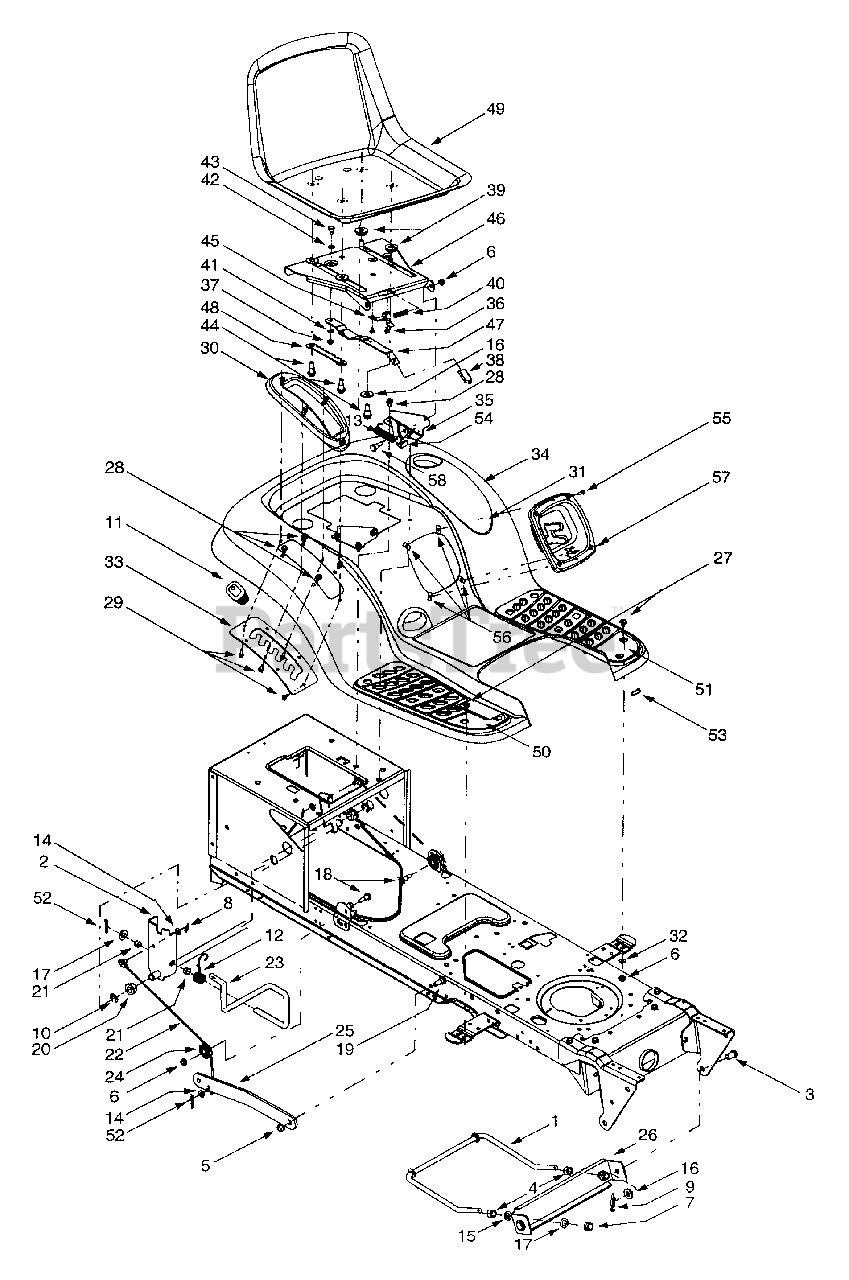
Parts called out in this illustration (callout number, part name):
1	Deck Stabilizer Rod
3	Clevis Pin, .5 x .78
4	Hex Nut, 1/2-13
5	Flange Lock Nut, 3/8-16
6	Flange Lock Nut, 5/16-18
7	Hex Nut, 1/2-13
8	Internal Cotter Pin
9	Internal Cotter Pin
10	E-ring
11	Handle Grip
12	Torsion Spring
13	Extension Spring, .872 x 3.4
14	Flat Washer, 5/16
15	Lock Washer, 1/2
16	Flat Washer, .31 x 1.062 x .134
17	Flat Washer, .51 x 1.12 x .06
18	Hex Cap Screw, 5/16-18 x .62
19	Shoulder Screw, 3/8-16
20	Hex Flange Bearing
21	Snap Flange Bearing
22	Lift Cable, 16.16
23	Lift Handle
24	Roller Pulley
27	Carriage Bolt, 5/16 x .62
28	Self-tapping Screw, 5/16-18 x .625
29	Self-tapping Screw, 1/4-15 x .75
30	Lift Lever Cover
31	Cover w/ Cup Holder
32	Flat Washer, .349 x 1.0 x .063
36	Screw, #10-16 x .375
37	Hex Flange Lock Nut, 1/4-20
38	Seat Adjuster Grip
39	Spacer
40	Compression Spring, .41 x 1.5
41	Spring Washer, .265 x .562 x .025
42	Flat Washer, .344 x .62 x .03
43	Shoulder Screw, .340 x .285, 1/4-20
44	Shoulder Screw, .50 x .50, 3/8-16
45	Seat Stop
48	Seat Adjustment Selector
49	High Back Seat w/ Drain Holes, Yellow
50	RH Foot Pad
51	LH Foot Pad
52	Cotter Pin
53	Trim Strip
54	LH Seat Lift Bracket
55	Phillips Pan Screw, 1/4-20 x .75
56	U-type Speed Nut, 1/4-20
57	Shift Lever Cover
